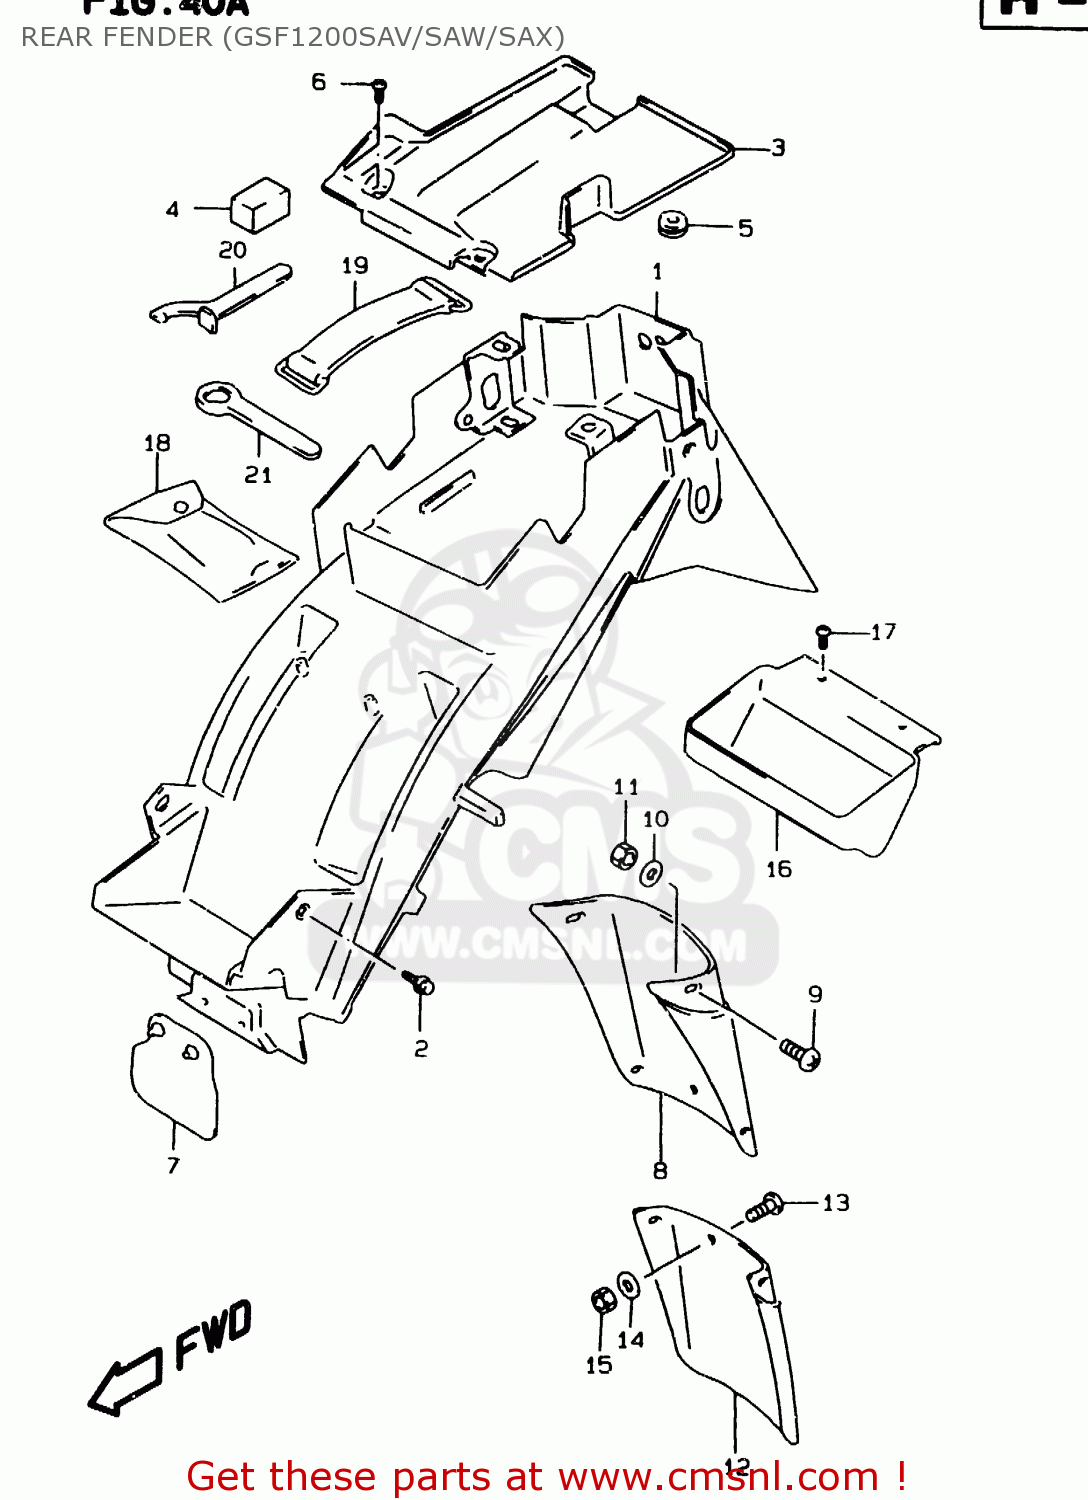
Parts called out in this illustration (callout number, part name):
1	FENDER,RR
2	BOLT
3	COVER,ECU
4	CUSHION,ECU COVER
5	CUSHION
6	SCREW
7	GUIDE,RR FENDER MUD
8	EXTENSION,RR FENDER
9	SCREW
10	WASHER(6.5X18X1.6)
11	NUT 6MM
12	MUDGUARD,RR FENDER EXTENSION
13	SCREW
14	WASHER(6.5X18X1.6)
15	NUT 6MM
16	HOLDER,TOOL
17	SCREW
18	TOOL ASSY
19	BAND
20	CLAMP
21	RING,SPANNER(24)
